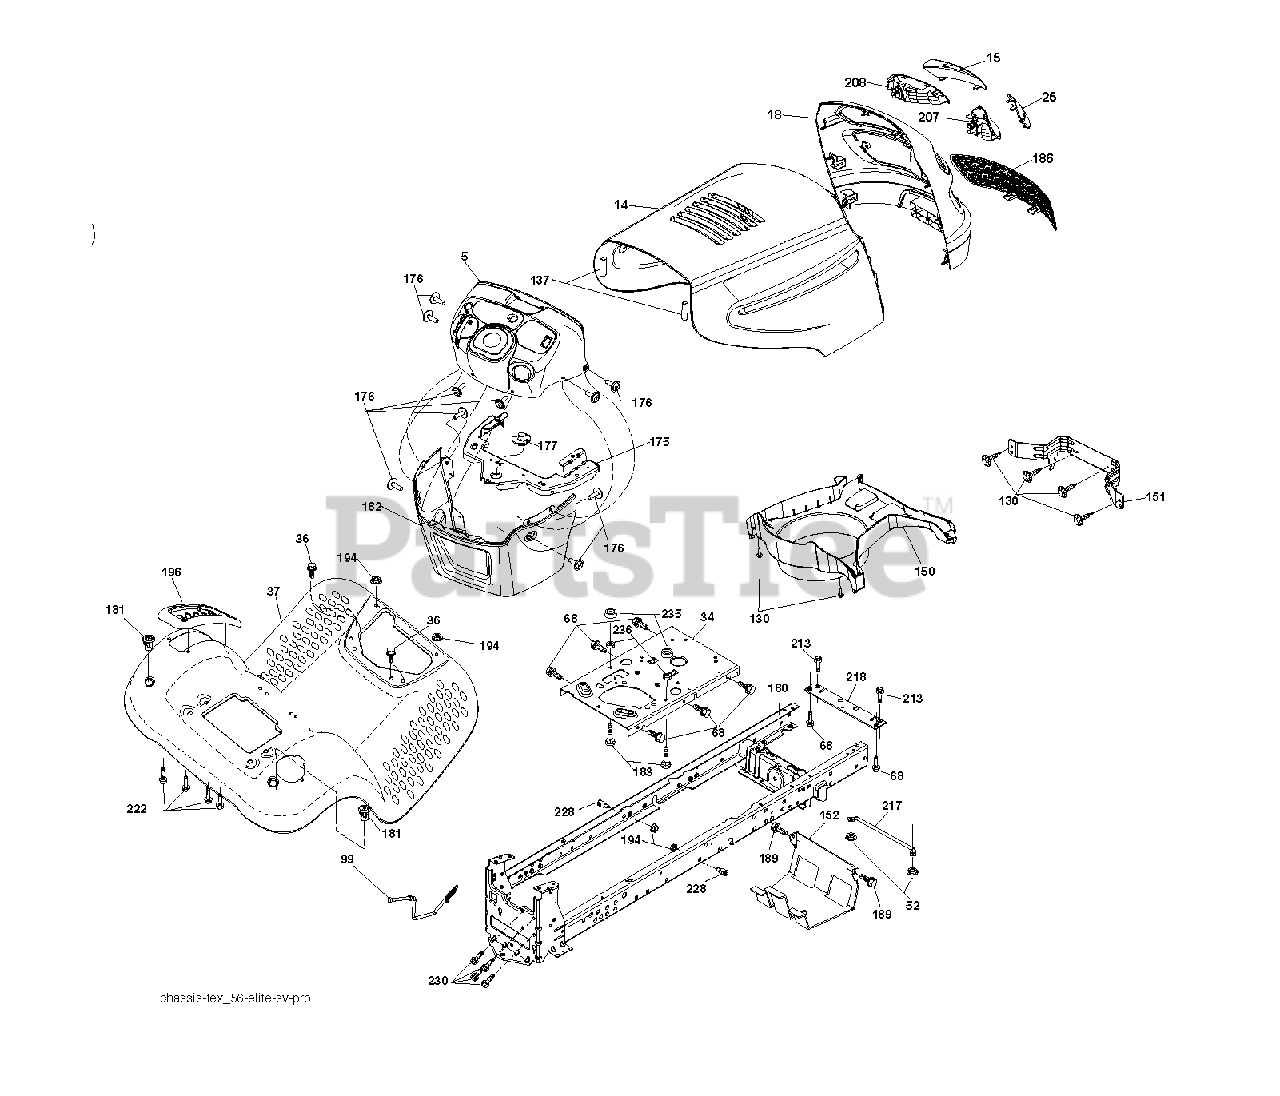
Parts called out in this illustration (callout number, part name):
34	PLATE.ENGINE.WELDED.CHASSIS
36	SCREW 5/16"
52	LOCKNUT
99	ROD ASM BYPASS
130	SCREW
137	BUMPER.HOOD.LARGE.1.75"
151	BRACKET PIVOT
152	SHIELD BROWNING
175	CROSSMEMBER.LT
176	SCREW.#10-24X5/8.RN.QU
177	BUSHING STEERING
180	CHASSIS
181	FEND/FTRST.PCH.CPH.NFW
182	DASH.LOWER.LT.CCS
183	BOLT.5/16-18X1-1/4 FULL.THREAD
189	SCREW
194	NUT LOCK HEX FLANGE 5/16-18
196	CONSOLE.ASM.DECK.LIFT.TLT.BLAC
207	BEZEL GRILL RH
208	BEZEL GRILL LH
213	BOLT
217	ROD PIVOT CHASSIS/HOOD
218	X-PIECE.HOOD.STOP.NON/
222	SCREW.1/4-20X5/8
228	STUD.FASTNER.W/ANTI-ROTATE
230	SHOULDER BOLT 5/16-18TT
235	SPACER FENDER
236	NUT.CENTERLOCK.5/16-
